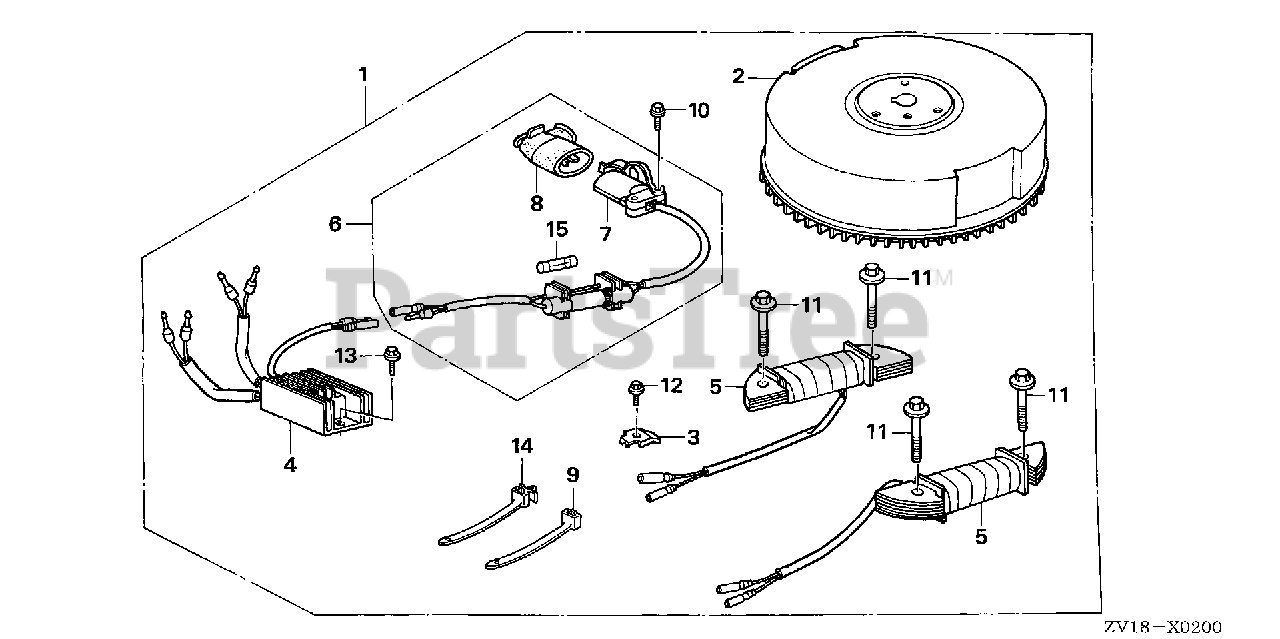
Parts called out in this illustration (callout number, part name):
1	RECEPTACLE KIT, CHARGE
1	RECEPTACLE KIT, CHARGE *TBLACK* (BLACK)
2	FLYWHEEL (CHARGE)
2	FLYWHEEL *TBLACK* (CHARGE) (BLACK)
3	CLAMP, WIRE
4	RECTIFIER ASSY., REGULATOR
5	COIL ASSY., CHARGE (12V/1.5A)
6	RECEPTACLE ASSY., CHARGE
7	RECEPTACLE
8	PLUG, RECEPTACLE
9	TIE, CABLE (2.4X92) (NATURAL)
10	BOLT, FLANGE (5X22)
11	BOLT, FLANGE (6X28) (CT200)
12	BOLT, FLANGE (5X10) (CT200)
13	BOLT, FLANGE (6X16)
14	BAND, CABLE
15	FUSE A (5A)
